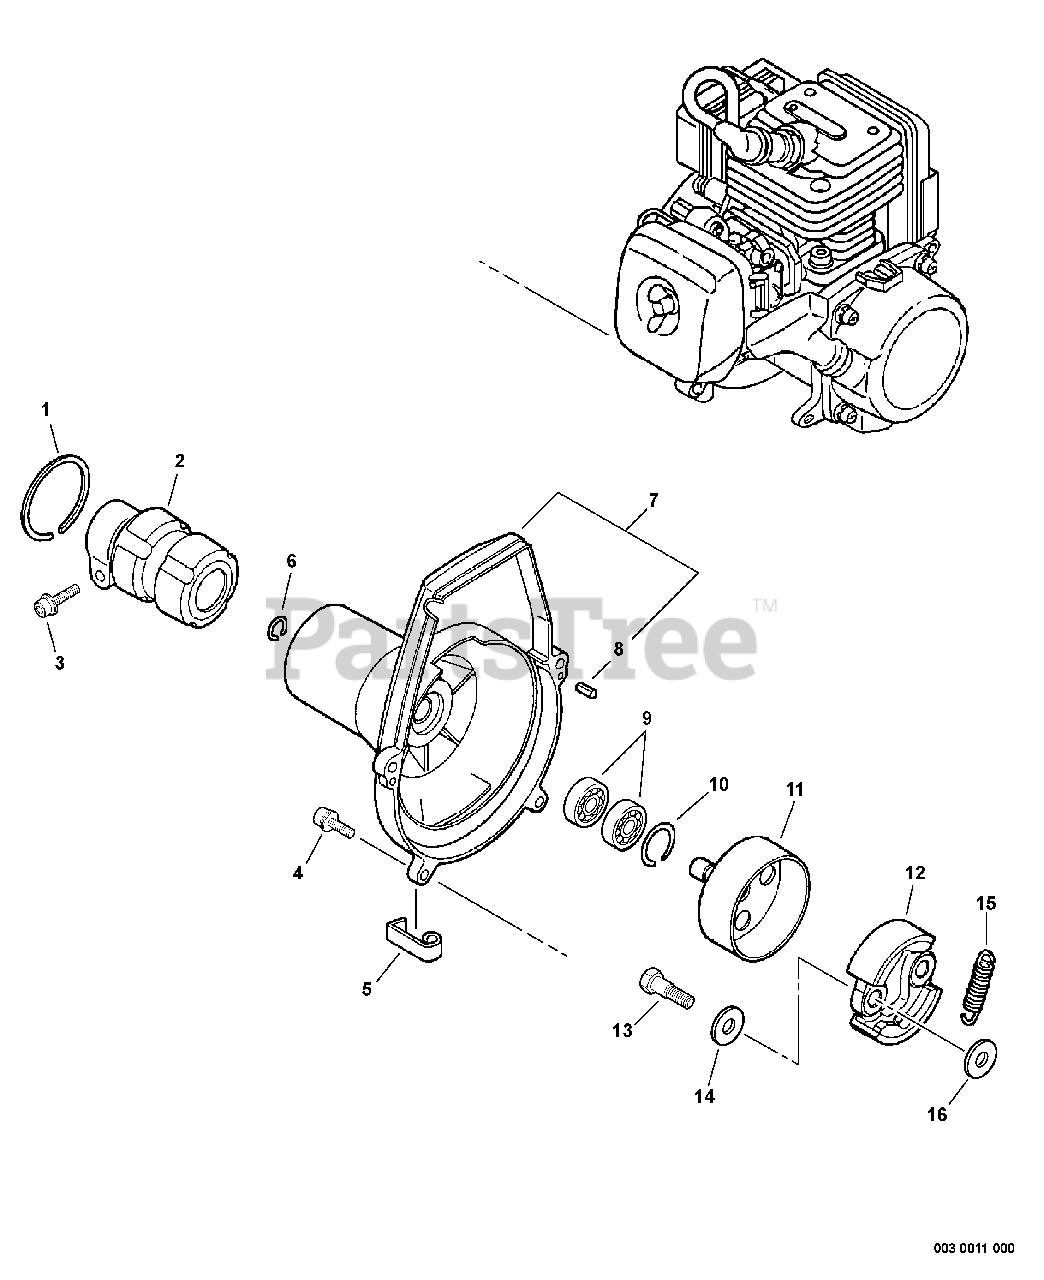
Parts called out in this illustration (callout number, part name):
1	RING, RETAINING - 42
2	CLAMP, MAIN PIPE
3	SCREW - 5X28
4	SCREW - 5X18
6	RING, RETAINING - 12
7	FAN CASE ASSY - ORANGE
8	PIN - LOCATING
9	BEARING, BALL - 6001
10	RING, RETAINING - 28
11	DRUM, CLUTCH
12	SHOE, CLUTCH
13	BOLT, CLUTCH
14	WASHER - SPRING
15	SPRING, CLUTCH
16	WASHER - 6
